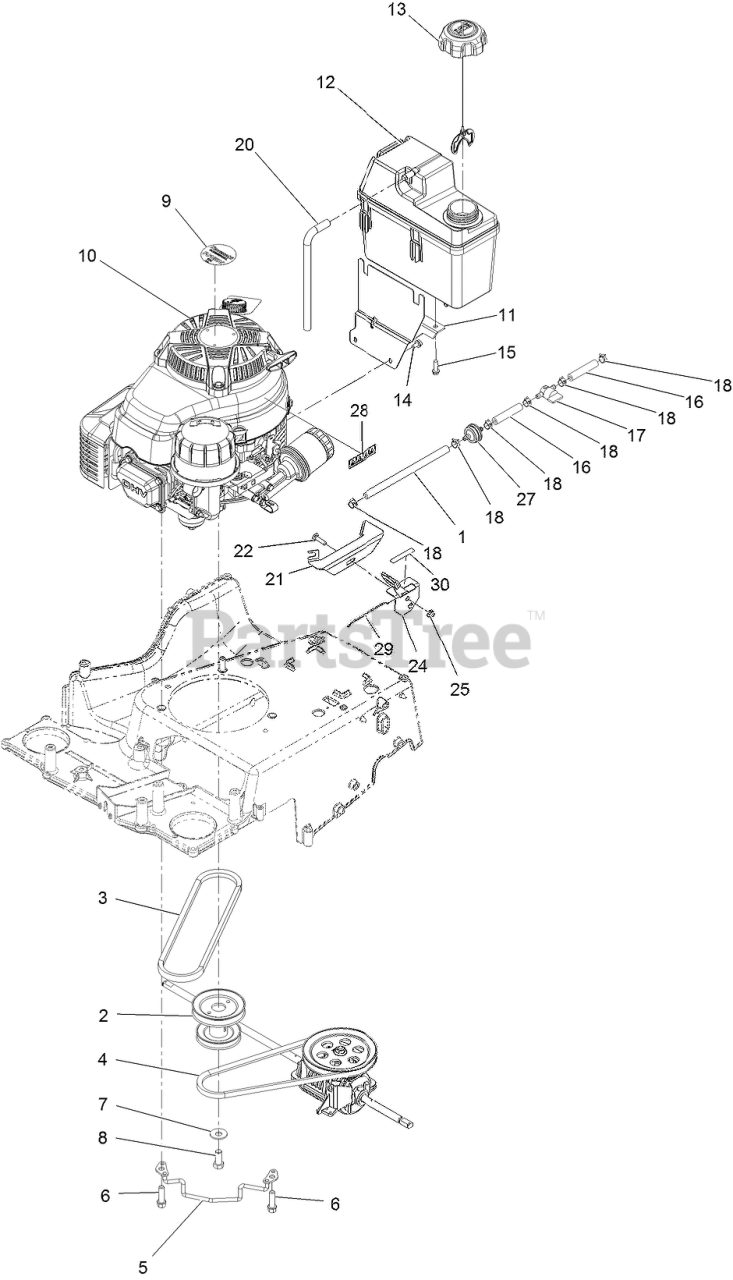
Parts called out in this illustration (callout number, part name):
1	HOSE-FUEL
2	PULLEY-ENGINE
4	BELT
5	GUIDE-BELT, WA
6	SCREW-TAPTITE
7	WASHER-BELLEVILLE
8	SCREW-HH
11	MOUNT-TANK
12	TANK-FUEL
13	CAP-FUEL
14	SCREW-HWH
15	SCREW-HWH
16	HOSE-FUEL
17	VALVE-FUEL
18	CLAMP-HOSE
20	HOSE-VENT, CANISTER
21	BRACKET-MOUNT, THROTTLE
22	SCREW-CARR
24	CONTROL-THROTTLE
27	Filter-Fuel
28	DECAL-WARNING, ENGINE
29	WIRE-CONTROL
30	DECAL-THROTTLE, CHOKE
